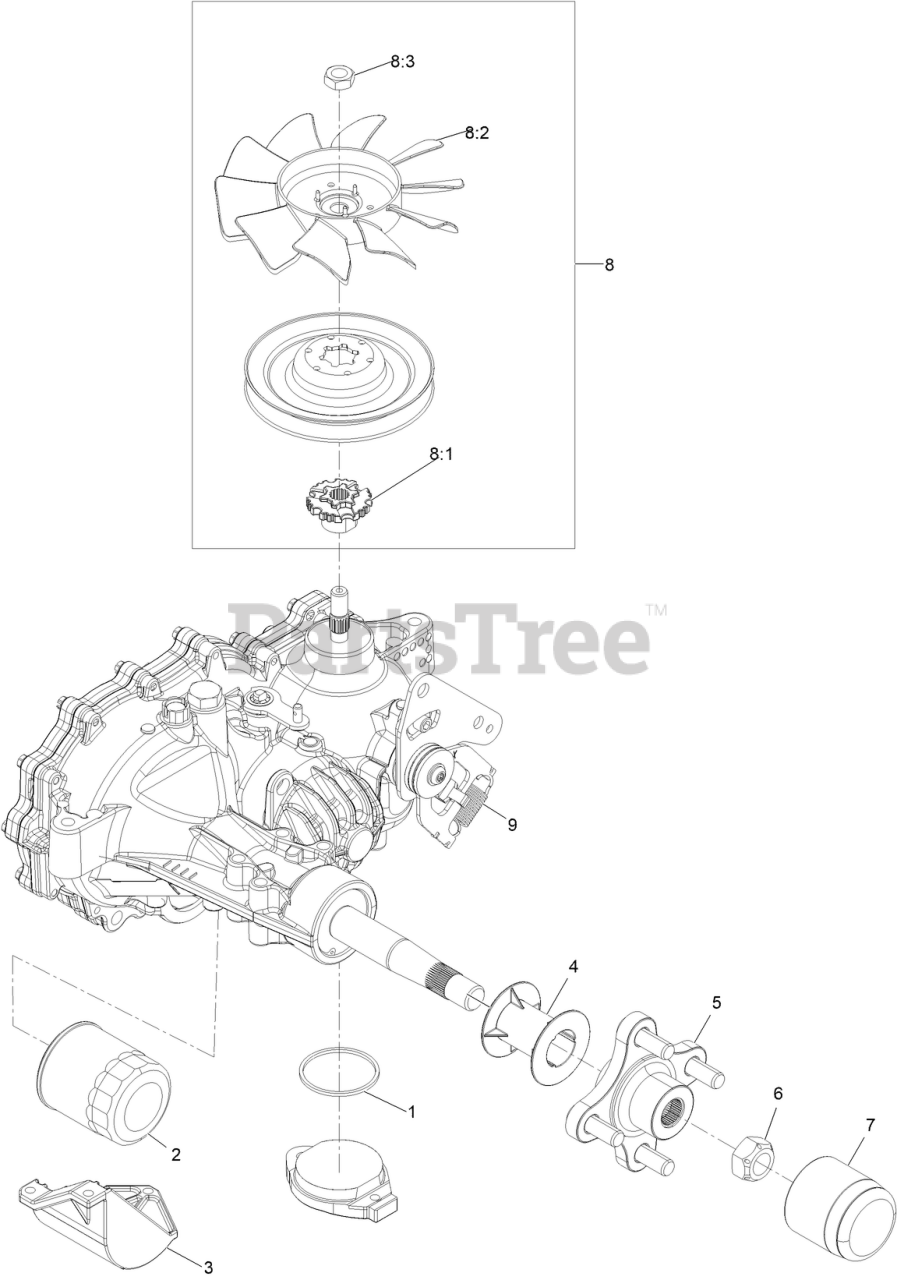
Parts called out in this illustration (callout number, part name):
1	O RING-SEAL
2	ELEMENT-OIL FILTER, HYD
3	GUARD-FILTER, RH
4	TUBE-AXLE
5	HUB-OFFSET
6	NUT-HUB
7	CAP-AXLE, LONG
8	FAN AND PULLEY KIT
8:1	HUB-FAN
9	SPRING-EXTENSION
